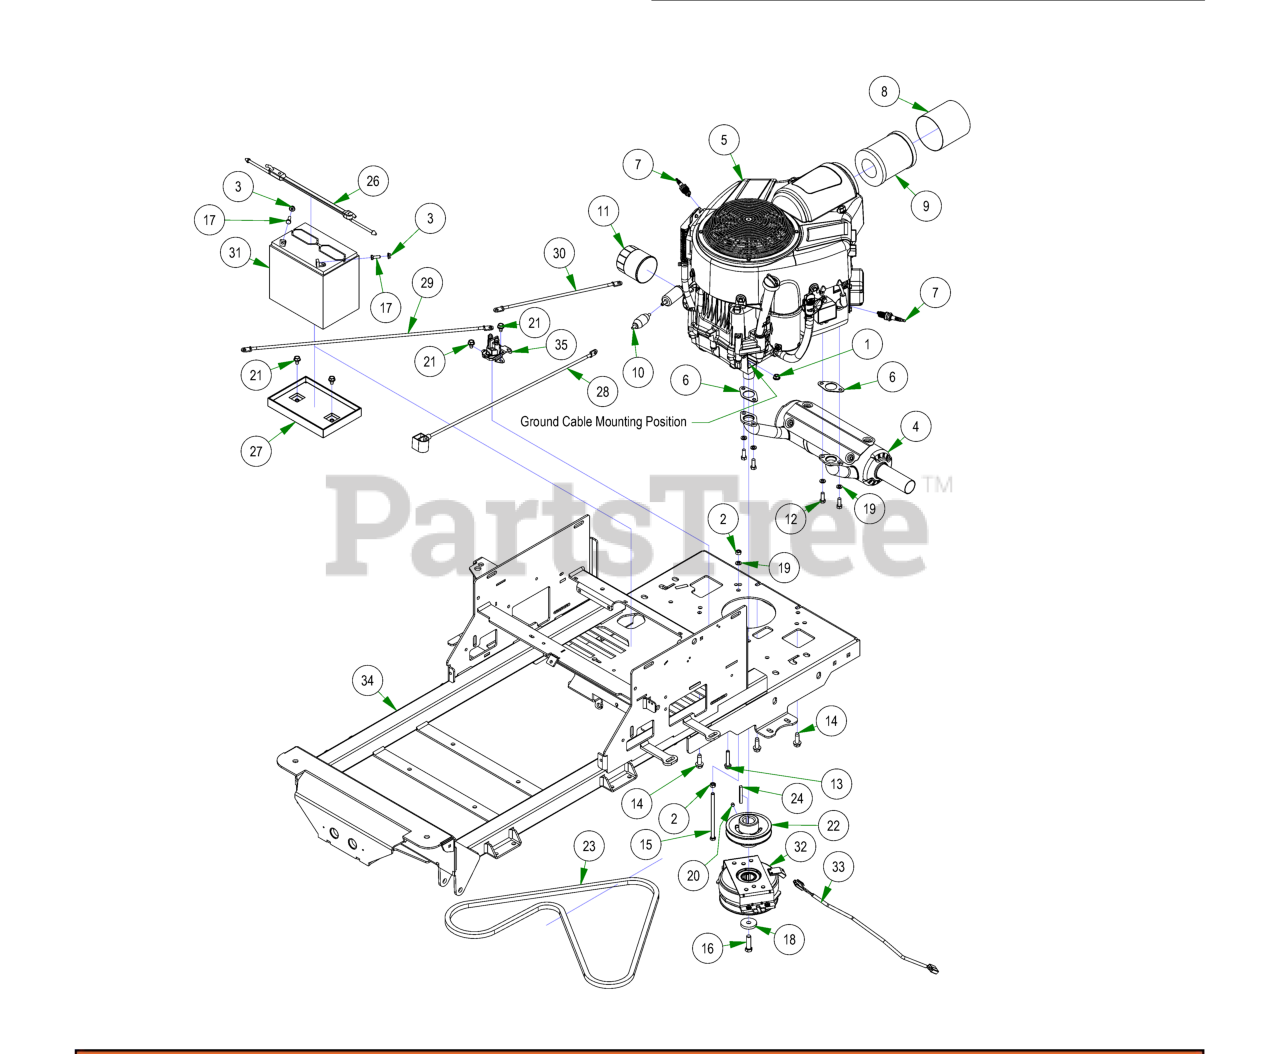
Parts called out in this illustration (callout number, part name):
1	5/16-18 Gr5 Distorted-Thread Flange Locknut
2	5/16-18 HEX NUT ZINC
3	1/4-20 HEX SERRATED FLANGE NUT HARD/ZINC
4	2017 Compact Outlaw Exhaust 810 Vanguard
5	Vanguard 27hp CXI with Out Oil Filter Maverick
6	Exhaust Gasket
7	Spark Plug
8	pre-Cleaner for Vanguard CXI Engine
9	Air Filter for Vanguard CXI Engine
10	Universal Inline Fuel Filter
11	Oil Filter
12	Torx Bolt-Exhaust
13	5/16-18x1-3/4 Gr5 Hex Flange Screw Zinc Clear
14	3/8-16 X 1-1/8 HEX WASHER UNSLOT SERRATED (TRI-LOB) TRS ZINC YELLOW
15	5/16-18 X 5-1/2 HEX CAP SCREW (GR.5) ZINC
16	7/16-20 X 1-1/2 HEX CAP SCREW (GR.8) w/ Patch
17	1/4-20 X 3/4 HEX CAP SCREW (GR.5) ZINC
18	CLUTCH WASHER
19	5/16 SPLIT LOCKWASHER ZINC
20	5/16-24 X 1/4 SOCKET SET SCREW (CUP PT) PLAIN
21	5/16-18 X 1/2 HWH unslot (F) tcs zinc
22	4 3/4 Motor Pulley
24	1/4 X 2 SQ MACHINERY KEY 1018 STL PLAIN
25	2023 Battery Hold Down Assembly
26	2023 Rubber Battery Hold Down Strap
27	Battery Tray
28	24 inch Black Cable – MZ/ZT
29	24" Red Battery Cable
30	12 in red battery cable
31	SP-35 Battery
33	Clutch Pigtail
34	2024 ZT Elite Frame
